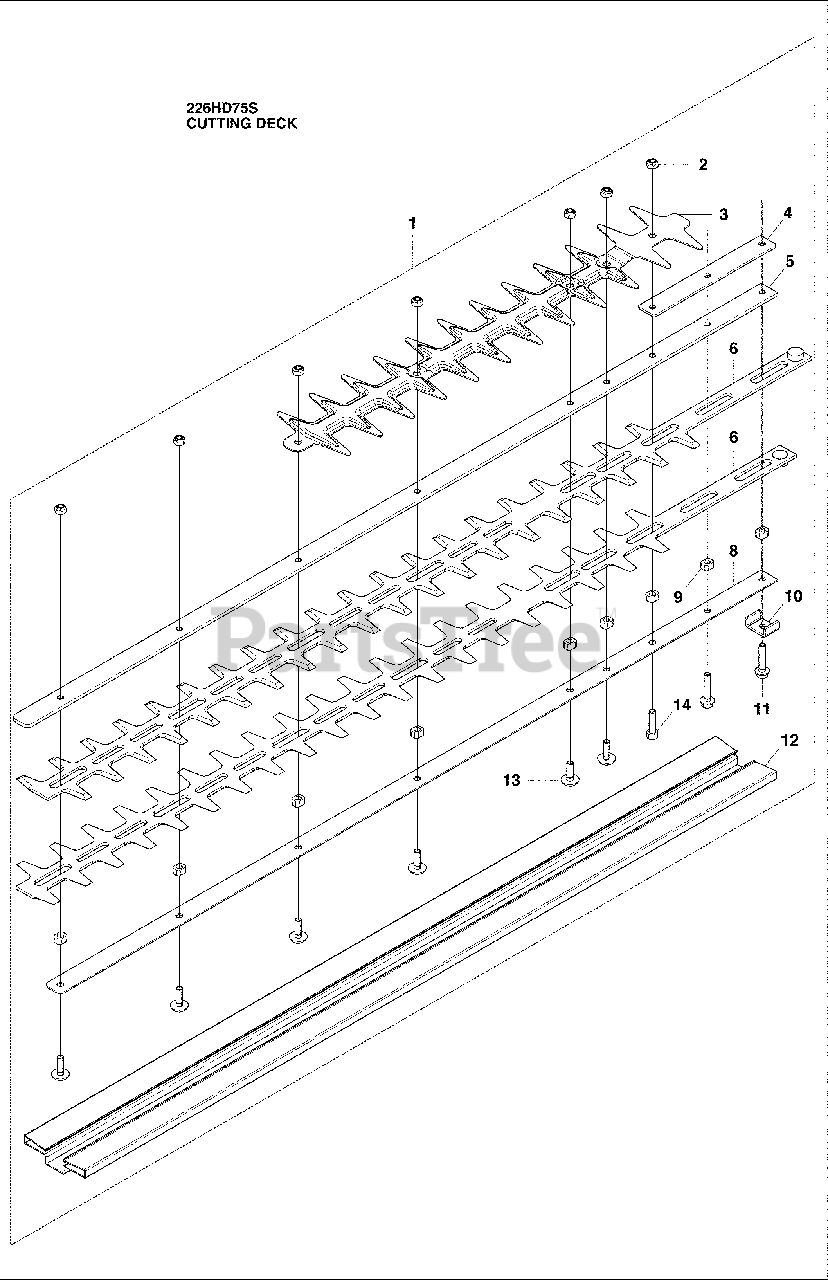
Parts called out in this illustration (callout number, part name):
1	Blade Assembly
3	Blade Guard
5	Plate, Upper
6	Blade, 226HD75S
8	Lower Plate
11	Bolt
12	Cover
14	Bolt
